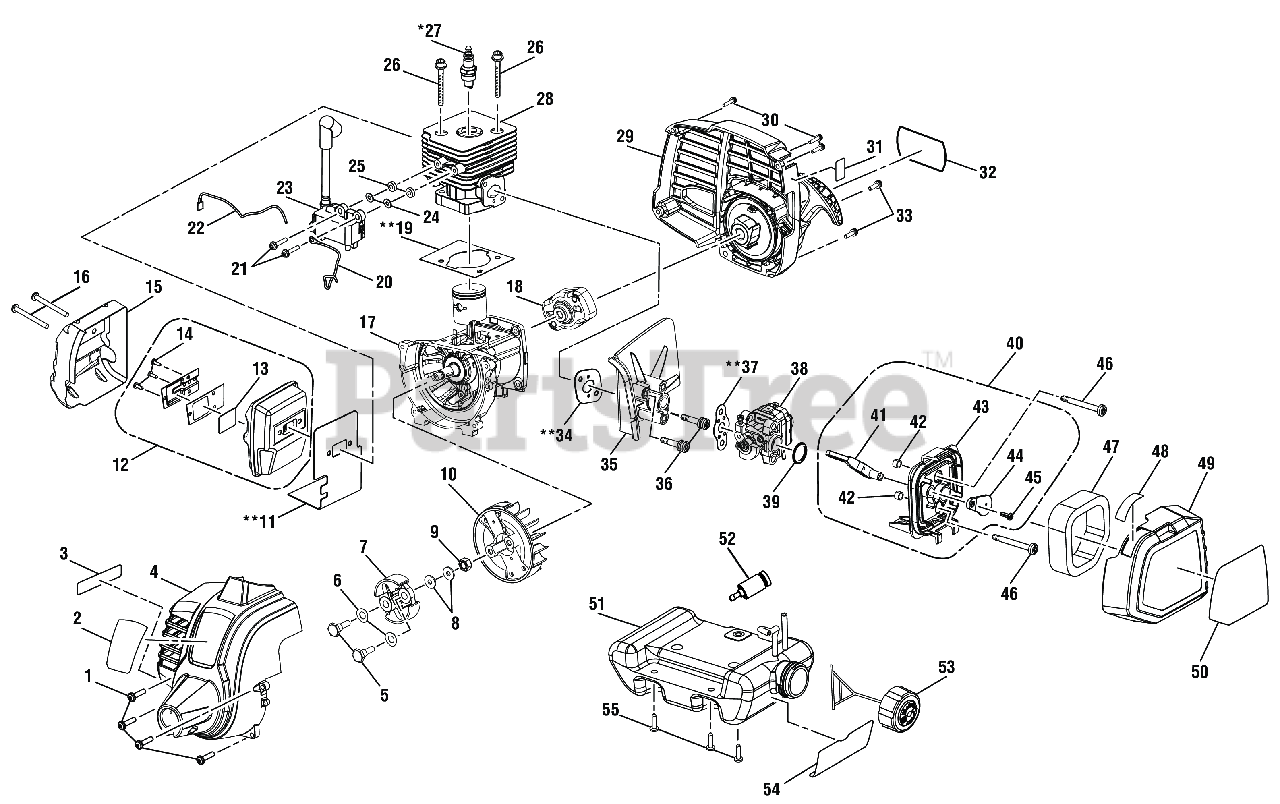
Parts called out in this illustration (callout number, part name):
1	Cap Screw w/Washer (M5 x 16 mm, T25 Torx Soc. Hd.)
2	Logo Label (Front)
3	Warning Label (Combustion)
4	Front Housing Assembly w/ Labels
5	Clutch Shoulder Bolt (M6 x 22.5 mm, Hex Hd.)
6	Washer (Curved)
7	Clutch Assembly
8	Washer (ID6 x OD15 x 1.2t)
9	Flange Nut (M8, Flywheel)
11	Muffler Gasket
12	Muffler Assembly
13	SCREEN
14	Screw (6-20 x 1/4 in., T20 Torx Pan Hd. S.T.)
15	HEAT SHIELD
16	Screw (M5 x 50 mm, Torx Slotted Recessed Pan Hd.)
17	Crankcase Assembly
18	Starter Cup
19	Gasket
20	Lead Wire Assembly, Red
21	Screw (M4 x 22 mm, T20 Torx Slotted Recessed Pan Hd.)
22	Lead Wire Assembly, Black
23	Coil Boot Assembly
24	Flat Washer (OD10 x ID42 x 1t)
25	Phenolic Spacer (Ignition Module)
26	Screw (M5 x 22 mm, T25 Torx Soc. Hd.)
27	Spark Plug (Champion RCJ6Y)
29	Screw (M4 x 18 mm, T20 Torx Pan Hd. S.T.)
30	Screw (M4 x 18 mm, T20 Torx Pan Hd. S.T.)
31	Primer Bulb Location Label
32	Shoulder Screw (M4 x 14 mm, T25 Torx Truss Hd.
33	Cap Screw w/Washers (M5 x 16 mm, T25 Torx Soc. Hd.)
34	Heat Dam Insulator
35	Screw (M5 x 30 mm, T25 Torx Pan Hd. S.T.)
36	Screw w/Washers (M5 x 30 mm, T25 Torx Pan Hd.)
37	Gasket
38	Carburetor Assembly
39	Carburetor O-Ring
40	Airbox Base Assembly
41	Compression Limiters
42	Washer (ID5.8 x OD11.5 x 1.7t)
43	Air Box Base
44	Screw (M4 x 12 mm, T20 Torx Pan Hd. S.T.)
45	Screw (M4 x 12 mm, Slotted Recessed Pan Hd.)
46	Screw (M5 x 44 mm,T25 Torx Hd. Carburetor)
47	Air Filter (Element)
48	Choke Position Label
49	Airbox Cover (Inc. Key Nos. 48 & 50)
50	Starting Instructions Label
51	Fuel Tank and Cap Assembly
52	Fuel Filter
53	Fuel Cap Assembly
54	Fuel Mixture Label
55	Shoulder Screw w/Washer (M4 x 14 mm, T25 Torx Truss Hd.)
